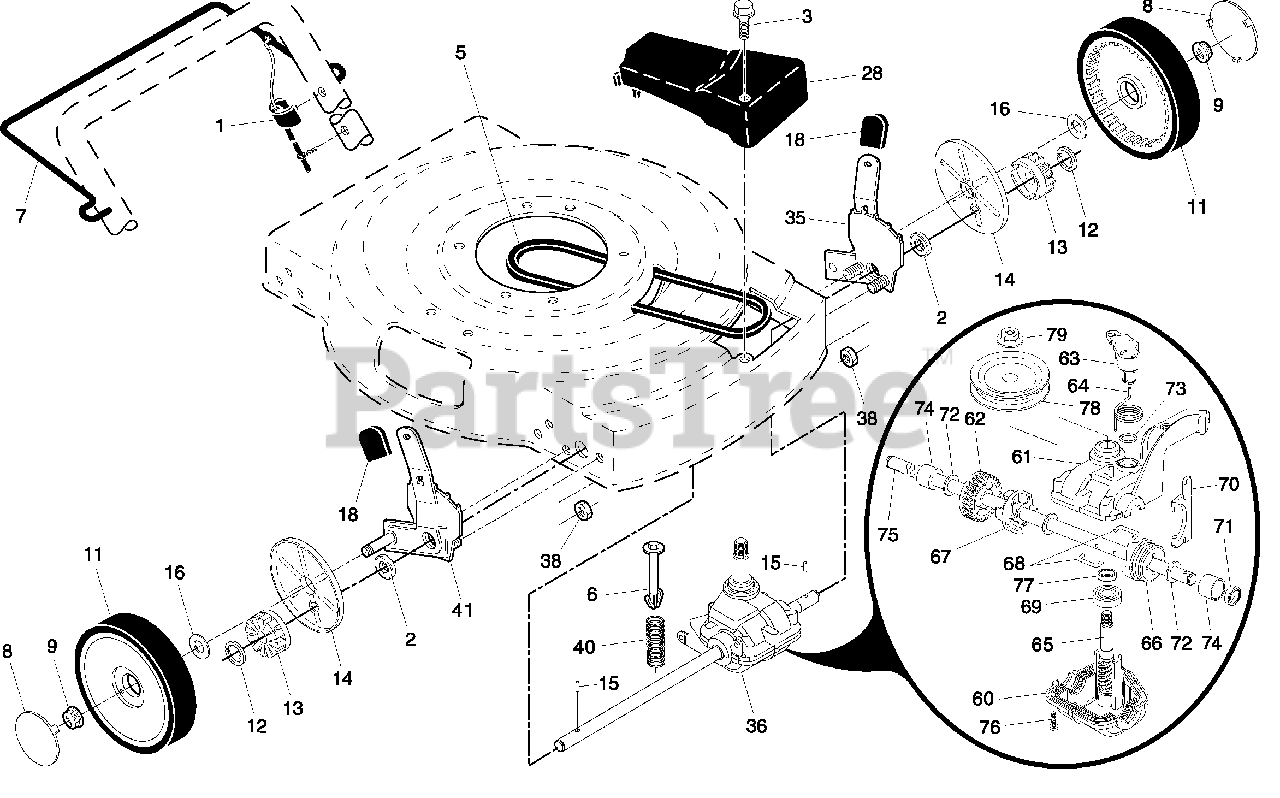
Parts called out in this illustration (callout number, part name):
1	Drive Control Cable Assembly
2	Bearing, Wheel Adjuster
3	Pan Head Tapping Screw #10-24 x 2-3/4
6	Spring Retainer
7	Control Bar, Drive
8	Hubcap
9	Locknut, Hex
11	Wheel & Tire Assembly
12	E-Ring
13	Pinion
14	Dust Cover
15	Pawl, Drive
16	Washer
18	Selector Knob
28	Drive Cover
35	Kit, Wheel Adjuster, LH
36	Gear Case Assembly, Complete
38	Locknut, Hex 1/4-20
40	Spring
41	Kit, Wheel Adjuster, RH
60	Case, Lower
61	Case, Upper
62	Gear, 27 Teeth
63	Lever, Clutch
64	Spring, Return
65	Shaft, Input
66	Dog, Movable
67	Dog, Fixed
68	Wire, Formed
69	Bearing, Ball
70	Fork, Shift
71	Seal, Output Shaft
72	Washer
73	Seal, Case
74	Bushing
75	Shaft, Output
76	Screw
77	Seal, Input Shaft
78	Pulley, Drive
79	Locknut, Hex
